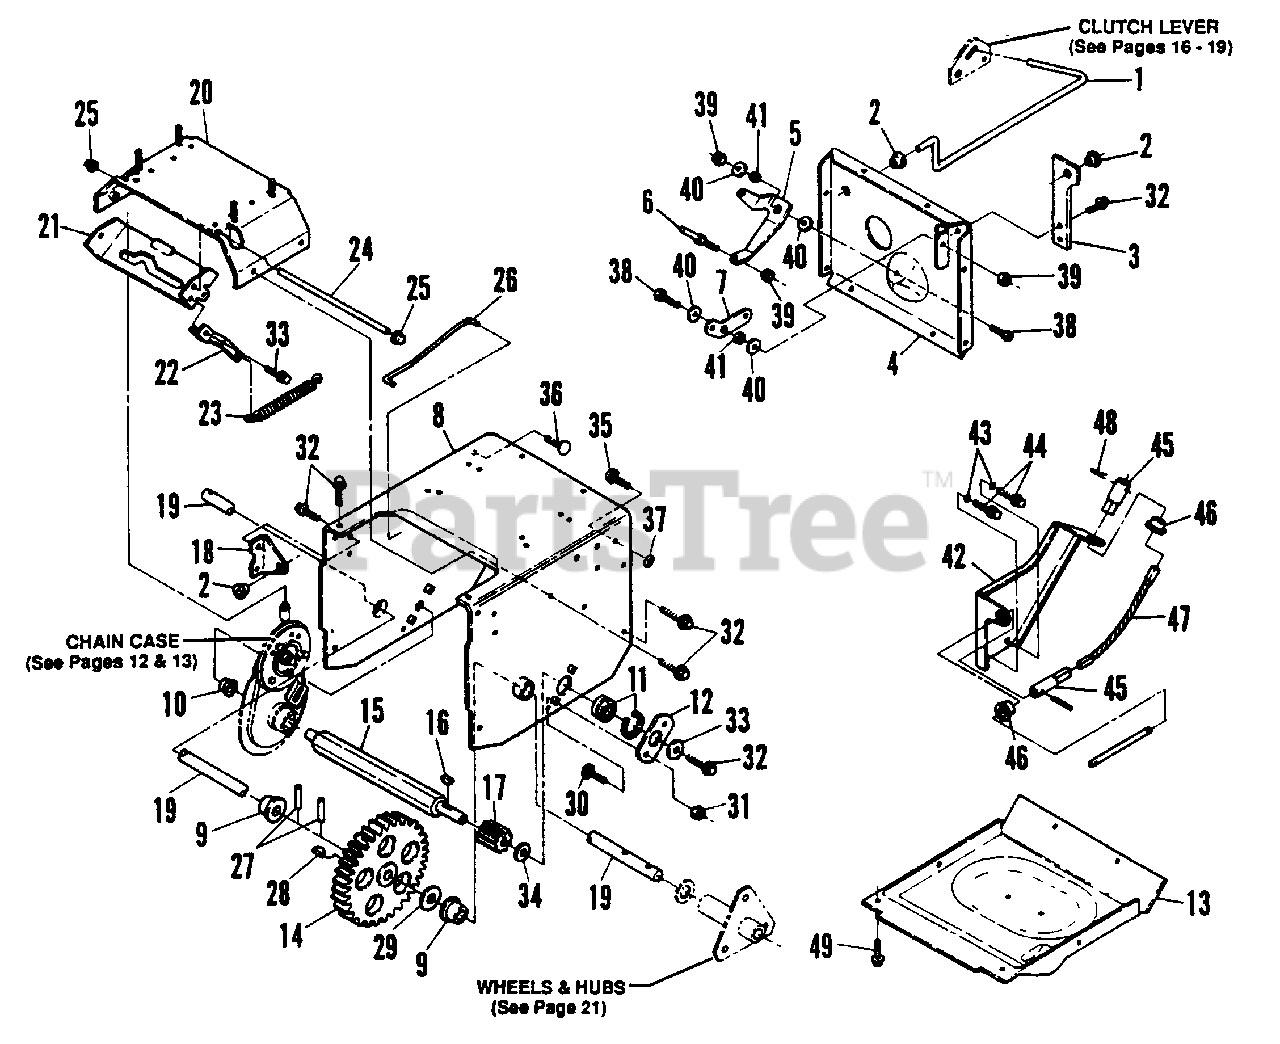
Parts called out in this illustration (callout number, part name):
1	ROD, Activating
2	BRACKET
3	BRACKET, Support
4	COVER, Frame Back
5	LEVER, Shift
6	STUD, Shift Lever
7	BELLCRANK, Traction
8	FRAME
9	BUSHING, Axle Shaft
10	BUSHING, Hex Shaft
11	BEARING
12	RETAINER, Bearing
13	COVER, Frame Bottom
14	GEAR, Axle Shaft
15	SHAFT, Hex
16	KEY, 1/8 x 5/8" Woodruff
17	PINION, Hex Shaft
18	BRACKET, Idler Mounting
19	SHAFT, Axle
20	BRACE, Frame 3.375 x 7.688
21	BRACKET, Clutch
22	BRACKET, Spring
23	SPRING
24	SHAFT, Cross
25	SCREW, 1/4-20 x 3/8" Hex Washer Self-Tap
26	ROD, Push
27	PIN, 3/16" x 1-1/4" Roll
28	KEY, 3/16 x 7/8" Woodruff
29	WASHER, 3/4 Thrust
30	BOLT, 1/4-20 x 1/2"
31	NUT, 1/4-20 Hex Flg. Lock
32	SCREW, 5/16-18 x 1/2" ST
33	WASHER, 3/8" Flat
34	WASHER, 5/8" Shim
35	BOLT, 5/16-18 x 3/4" Carr.
36	BOLT, 5/16-18 x 1-3/8" Carr.
37	RETAINER, 5/16" Bolt
38	SCREW, 5/16-18 x 3/4" Hex Head Cap
39	NUT, 5/16-18 Ctr Lock
40	WASHER, 5/16" x 1-1/4" x 3/32" Flat
41	SPACER, 5/16 x 5/8"
42	BRACKET, Flex Shaft
43	WASHER, 5/16" Split
44	SCREW, 5/16-18 x 5/8" HWST
45	CONNECTOR, Plastic
46	BUSHING
47	SHAFT, Flex
48	PIN, 1/8 x 3/4" Cotter
49	SCREW, 1/4-20 x 5/8" Hex Washer Self-Tap
